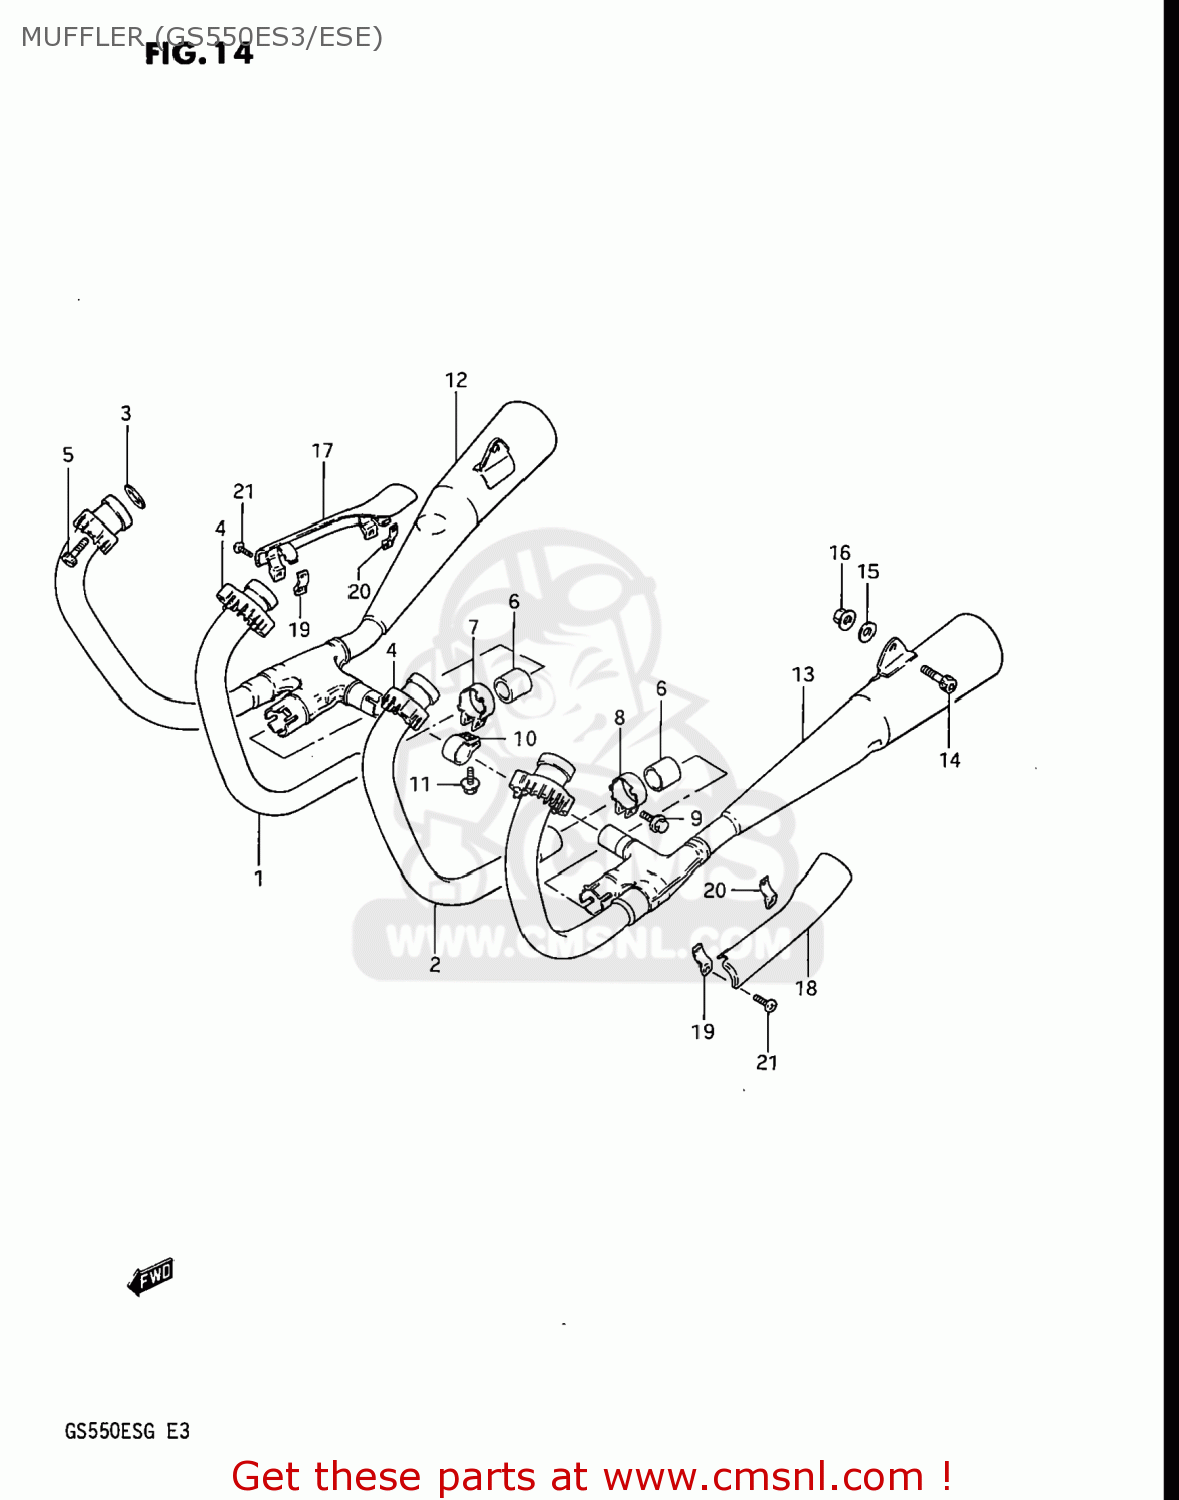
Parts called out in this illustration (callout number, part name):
1	PIPE,EXHAUST,CENTER,RIGHT
2	PIPE,EXHAUST,CENTER,LEFT
3	GASKET,EXHAUST PIPE (NAS)
4	CLAMP,EXHAUST PIPE
5	BOLT
6	CONNECTOR,MUFFLER
7	CLAMP,MUFFLER CONNECTOR
8	CLAMP,MUFFLER CONNECTOR
9	BOLT
10	CLAMP,EXHAUST
11	BOLT
12	MUFFLER
13	MUFFLER,LEFT
14	BOLT
15	WASHER(10.5X20X3.2)
16	NUT
17	COVER,MUFFLER,RIGHT
18	COVER,MUFFLER,LEFT
19	CLAMP,MUFFLER COVER
20	CLAMP,MUFFLER COVER
21	SCREW
